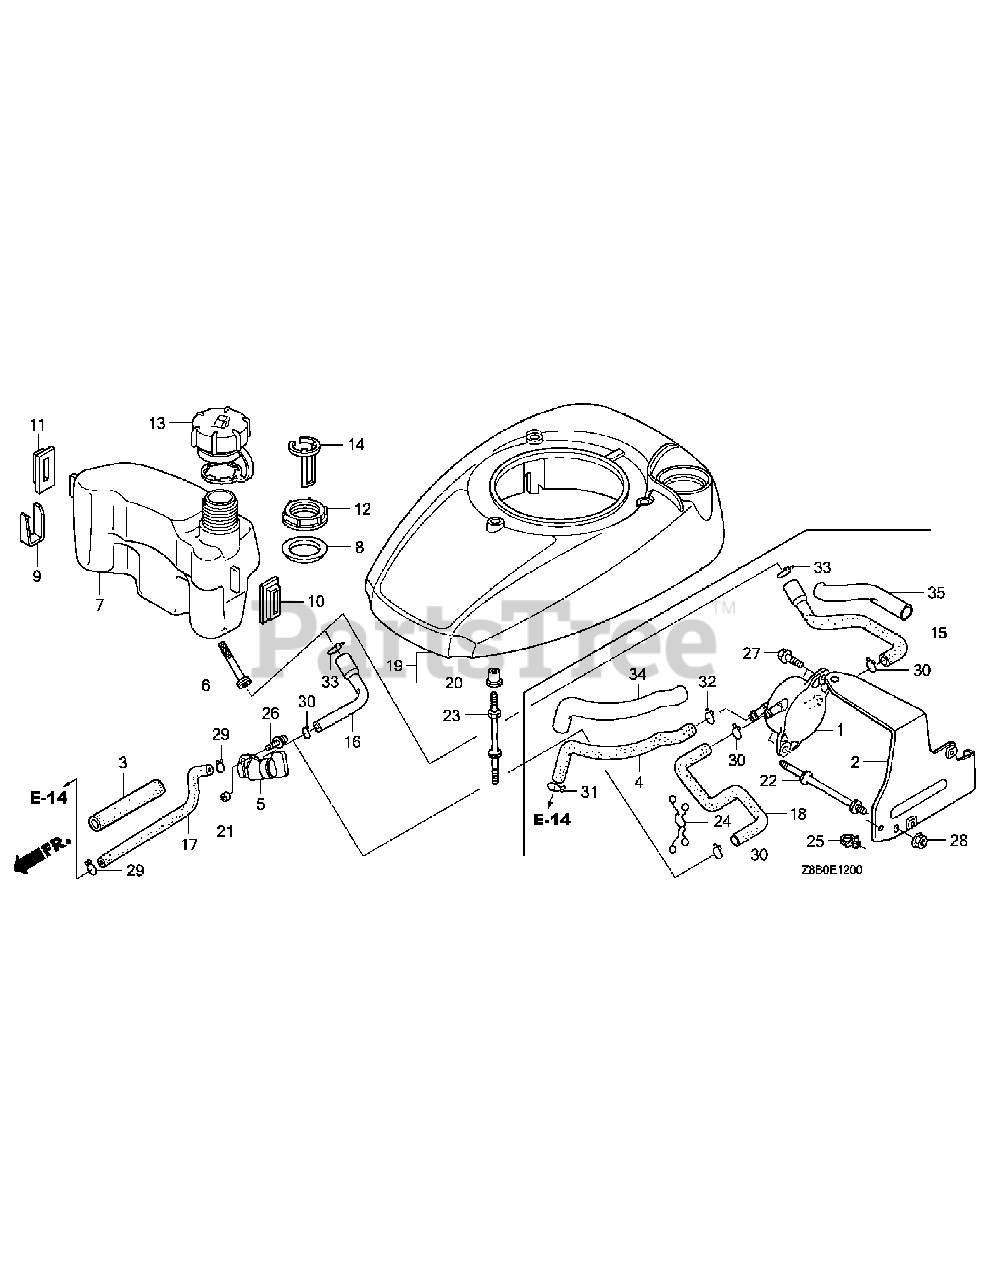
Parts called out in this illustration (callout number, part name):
3	RUBBER, SUPPORTER (107MM)
5	PETCOCK ASSY.
6	FILTER, FUEL
7	TANK, FUEL
8	SEAL, FUEL FILLER NECK
9	CLIP, TANK MOUNTING
10	RUBBER A, TANK MOUNTING
11	RUBBER B, TANK MOUNTING
12	NUT, TANK MOUNTING
13	CAP ASSY., FUEL TANK
14	GAUGE, FUEL LEVEL
16	TUBE, FUEL TANK
17	TUBE, FUEL
19	COVER, FAN *NH1* (Honda Code 8572083). (BLACK)
20	COLLAR, FAN COVER
21	COLLAR, FUEL PETCOCK
23	BOLT, STUD (H=42.5MM)
26	SCREW-WASHER (5X10)
29	CLIP, TUBE (B8)
30	CLIP, TUBE (B10)
33	CLIP, TUBE (C11)
